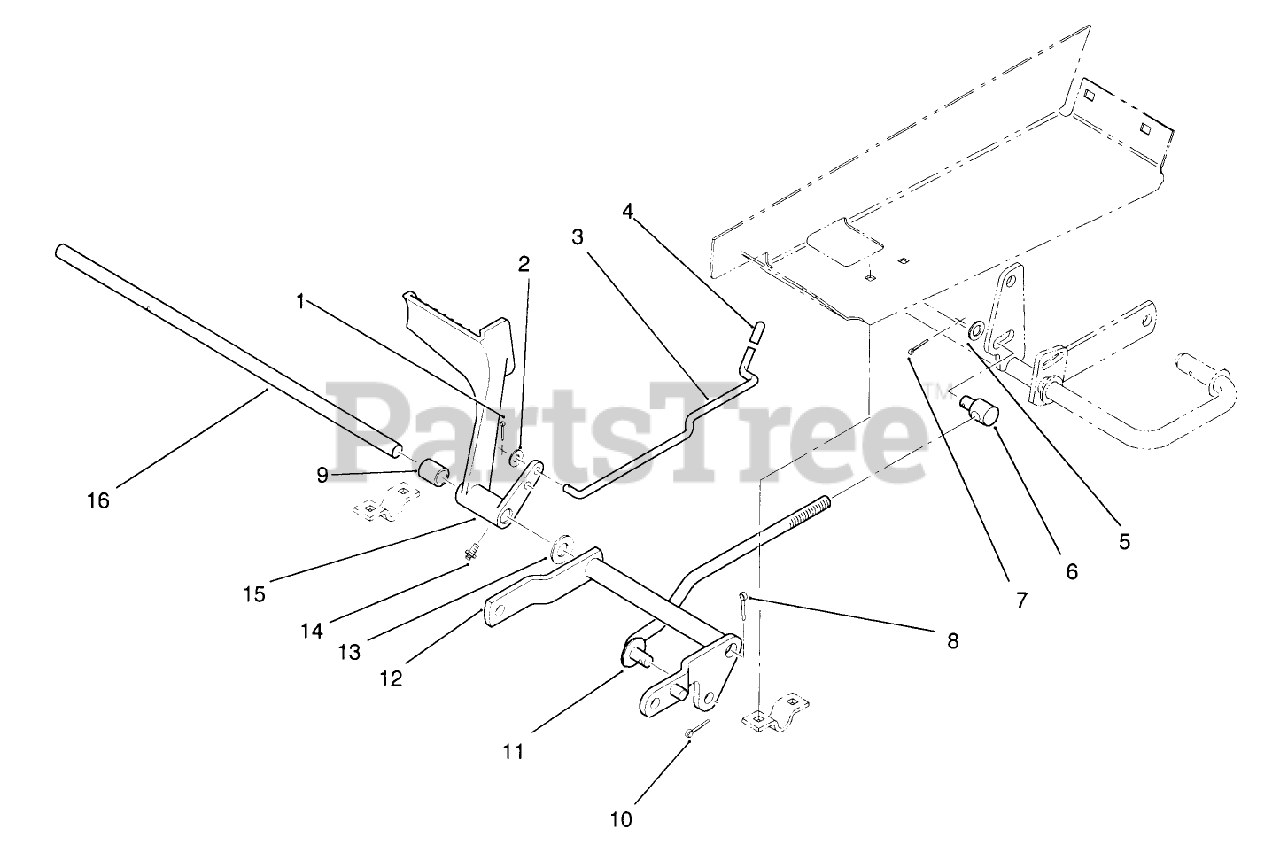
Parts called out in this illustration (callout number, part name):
2	WASHER 5/16 SAE
3	ROD-BRAKE LOCK
9	SPACER
16	SHAFT *R
